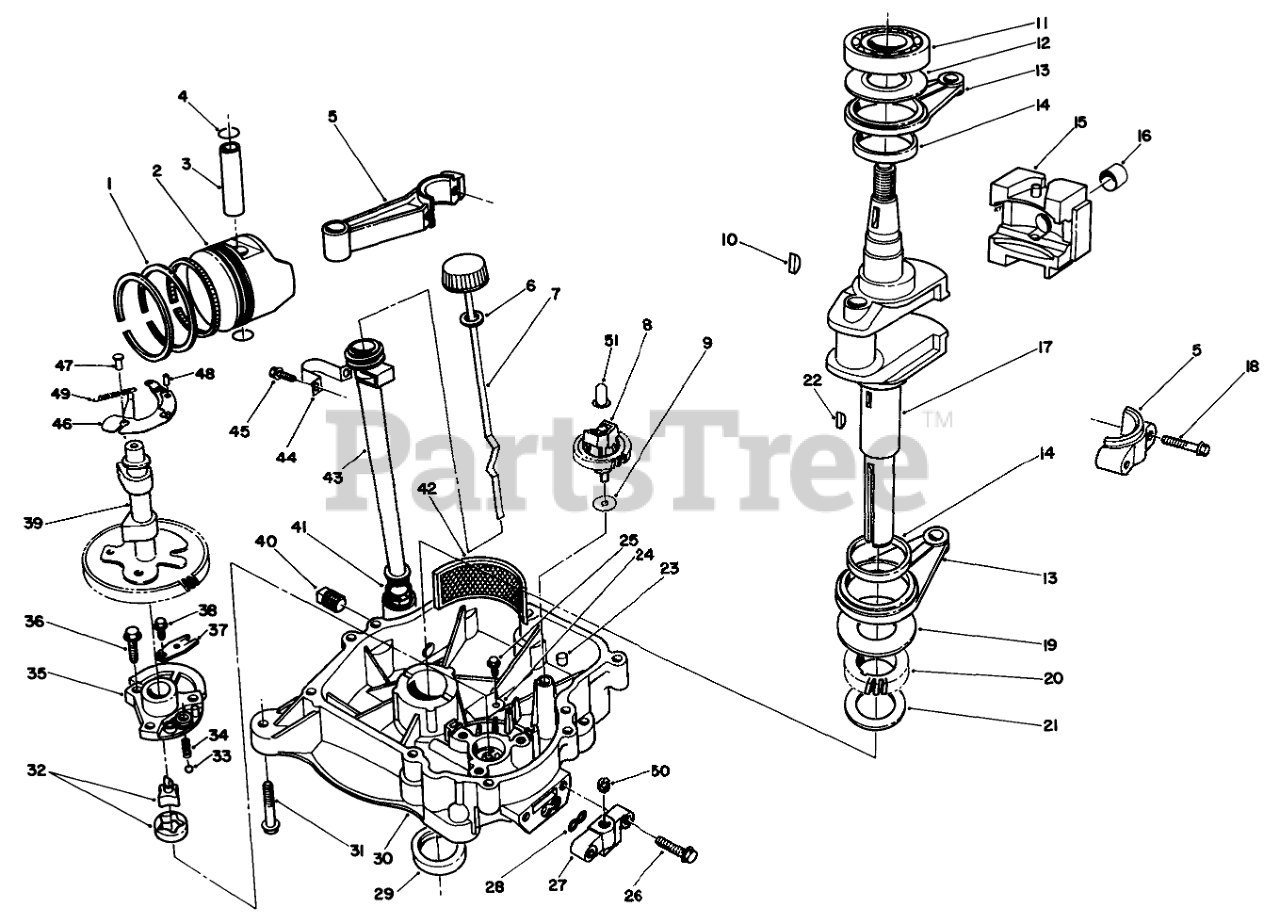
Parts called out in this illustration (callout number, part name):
1	Piston Ring Set
3	Pin-Piston
4	Ring-Snap
5	Rod ASM Incl #10 11
6	Gasket
8	Governor ASM
11	Ball Bearing
13	Rod Incl #8
15	Weight
17	Crankshaft
20	Gear
21	Shim (1.18)
25	Bolt
26	Bolt
31	Bolt-Flanged (8X45)
32	Pump ASM-Oil
35	Cover-Pump
36	Bolt-Flanged (8X25)
37	Plate
38	BOLT-FLANGED (6X10)
39	Camshaft
40	Plug
41	O-RING (16mm)
42	Filter-Oil
45	Bolt
46	Decompressor
51	Sleeve
